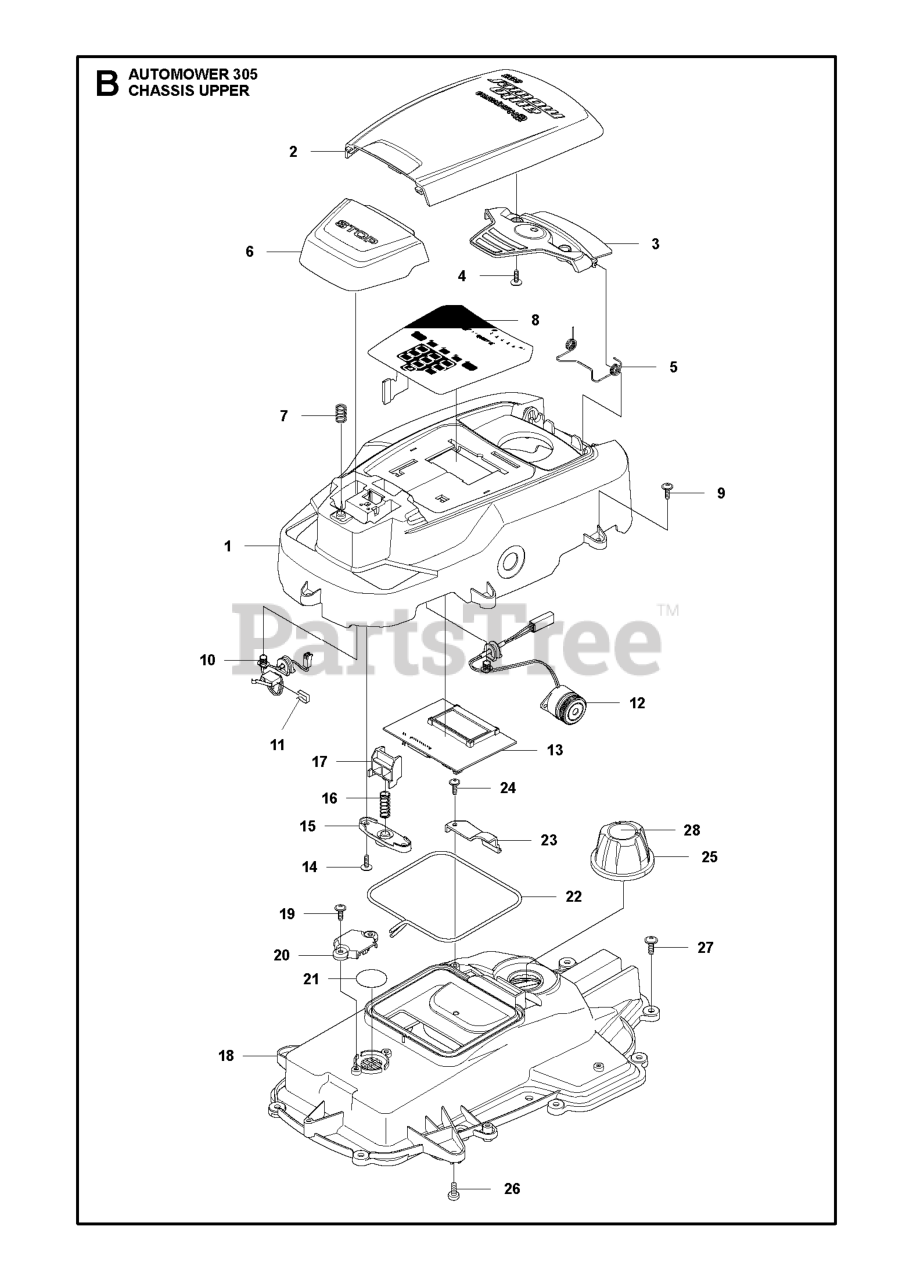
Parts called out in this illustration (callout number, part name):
4	SCREW 14MM
7	SPRING STOP BUTTON
9	SCREW 14MM
10	SWITCH STOP BUTTON
11	CLIP RETAINER
12	BUZZER DISPLAY COVER
14	SCREW 14MM
15	SPRING HOLDER STOP BUTTON
16	SPRING LOCK STOP BUTTON
17	LOCK STOP BUTTON
19	SCREW 14MM
20	COVER AIR FILTER
21	KIT AIR FILTER KIT 305 - 10 PC
23	COVER HEIGHT INDICATOR
24	SCREW 14MM
26	SCREW ITXPANM M5X12 8.8 ZP-BC
27	SCREW ITXPANT
